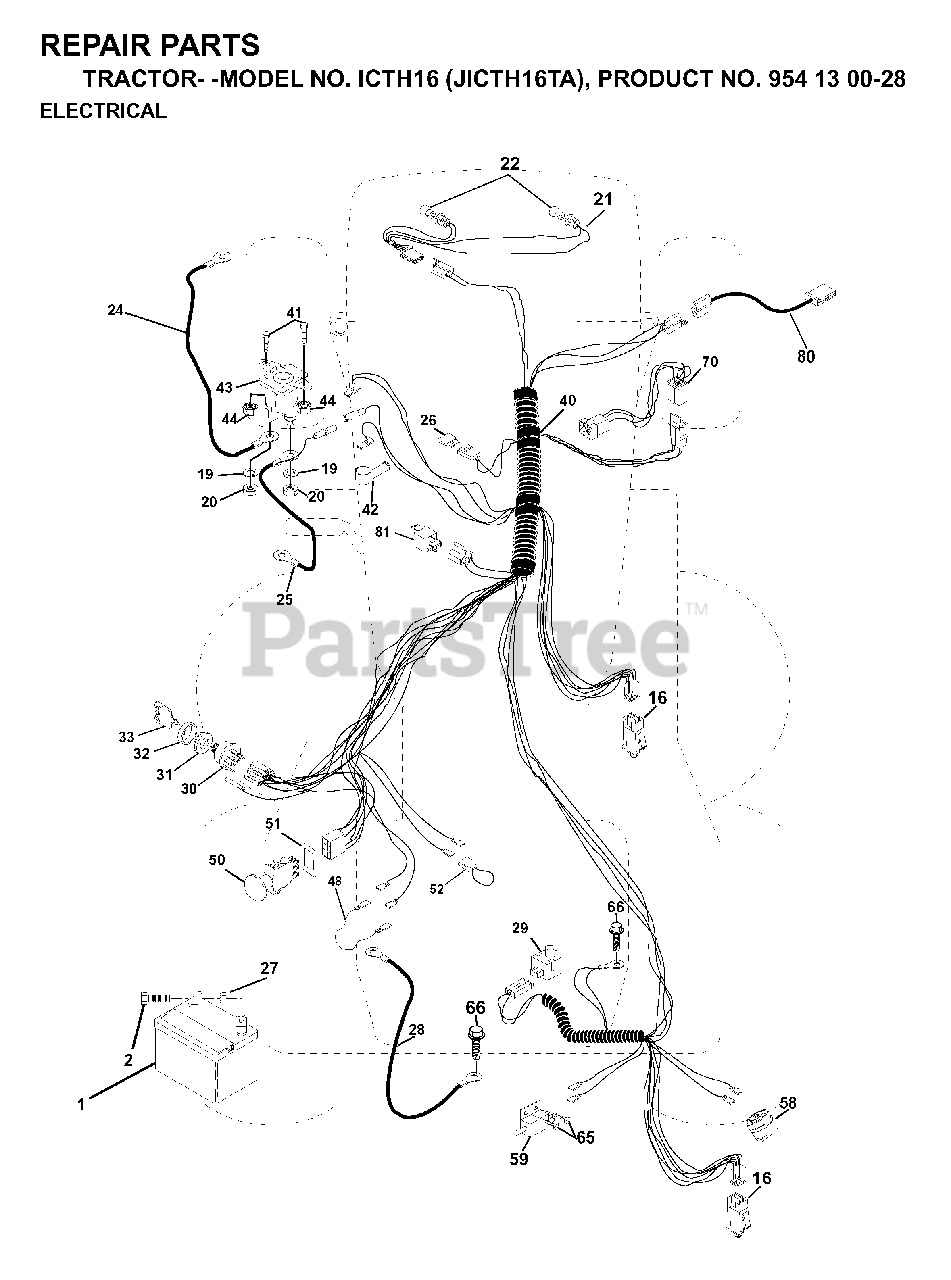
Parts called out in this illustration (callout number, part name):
1	BATTERY 12 VOLT 25 AMP
16	SWITCH INTERLOCK
19	LOCKWASHER
20	NUT
21	HARNESS ASM, LIGHT W/4152J
22	LIGHTBULB
24	CABLE ASM
25	CABLE BATTERY
26	FUSE 15 AMP
27	NUT
28	CABLE GROUND
29	PLUNGER SWITCH (COLOR:OLIVE)
30	SWITCH.IGNITION.4.POSITION
31	NUT IGNITION
32	COVER SWITCH KEY
42	TERMINAL COVER
43	SOLINOID
51	RETAINING RING
70	HARNES.ENG.TEC/KOHL
80	HARNESS, CLUTCH
81	RELAY.ASSY.T
